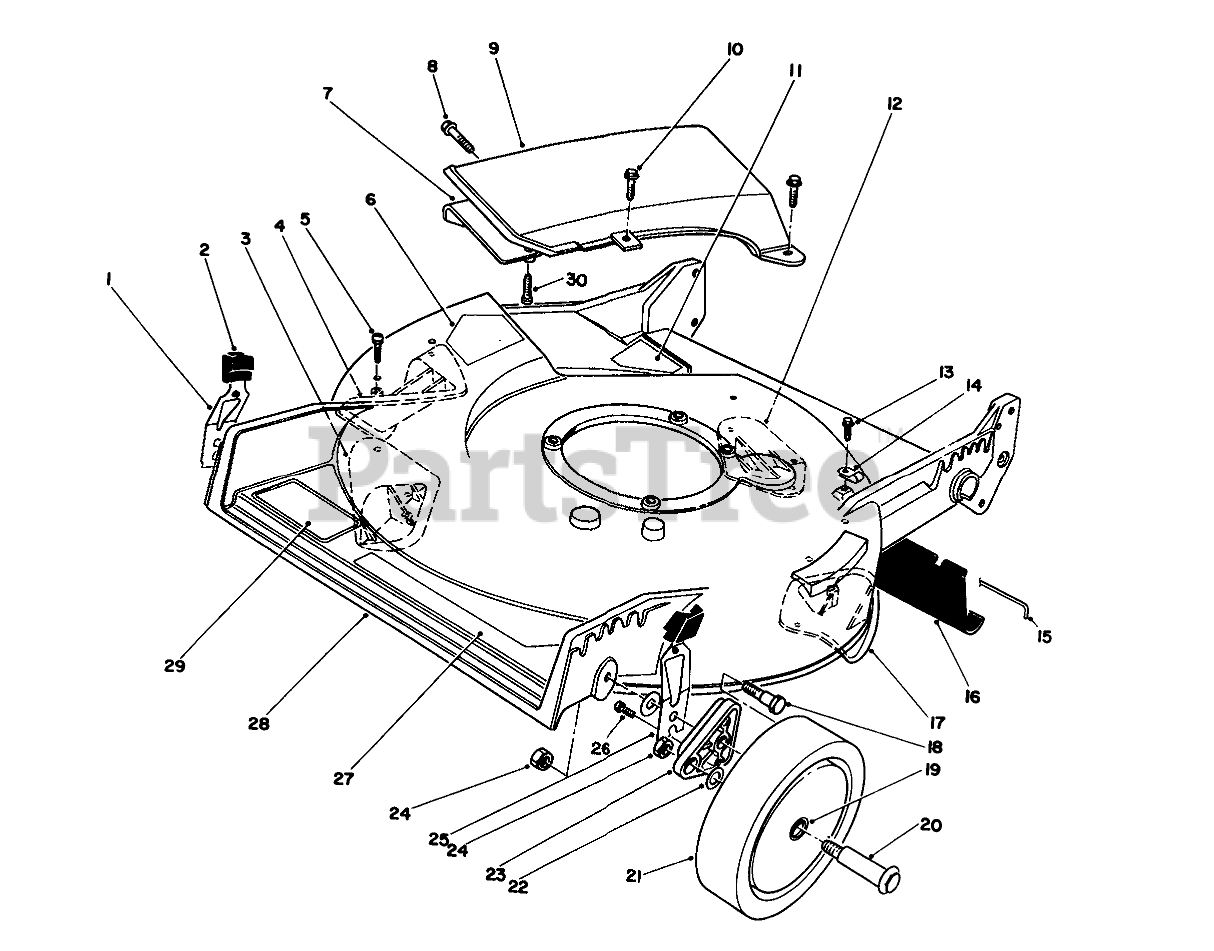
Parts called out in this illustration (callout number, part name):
1	RH SPRING ARM ASSEMBLY
2	KNOB-ARM
3	KICKER
4	KICKER
5	SCREW-PPH
6	DECAL-DANGER
7	Deflector-Recycler
8	SCREW AND WASHER ASM
9	Cover Assembly (Incl. Ref #7 & 19)
10	SCREW-HWH
11	DECAL - DANGER
12	PLATE-KICKER
13	SCREW-HWHTF
14	CLAMP-R
15	ROD-SHIELD
16	SHIELD-TRAILING
17	KICKER
18	SCREW-SHOULDER
19	BUSHING
20	WHEEL BOLT
21	Wheel & Tire Assembly (Incl. Ref. #19)
22	WASHER
23	ARM-PIVOT, FRONT
24	Nut
25	LH SPRING ARM ASSEMBLY
26	SCREW-HWH
27	DECAL - DECK
28	Housing Assembly (Incl. Ref. #3-6, 12, & 17)
29	DECAL
30	Screw-Pan Hd.
